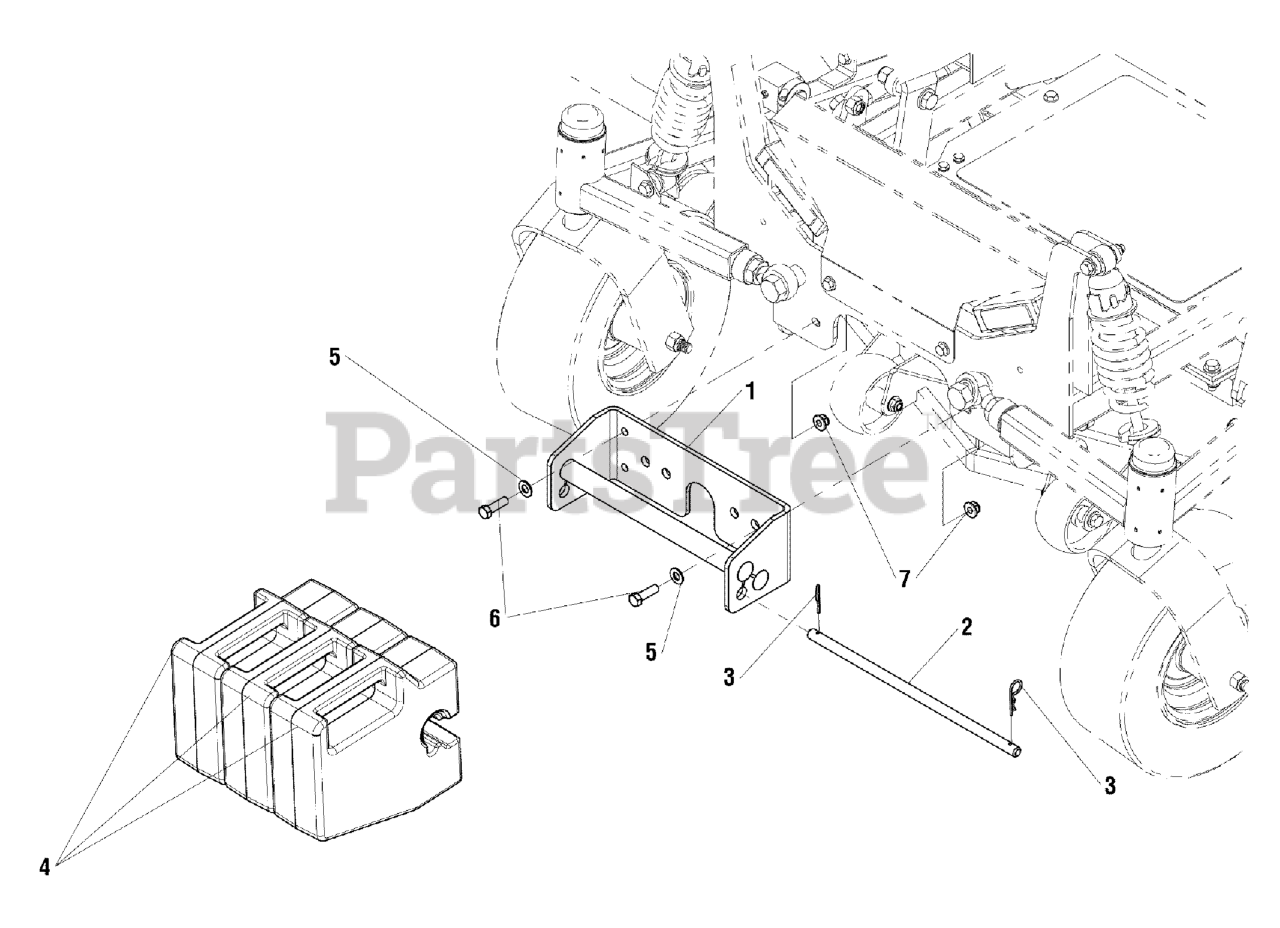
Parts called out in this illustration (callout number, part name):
1	HOLDER ASMY-WEIGHT CONS Z CAT - BLACK
2	ROD-.500DIA 13.75LG YELLOW CON
3	PIN, HAIR, .0915 X 1-7/8
4	WEIGHT-QUICK ATTACH 50LB SUITCASE PAINTED
5	WASHER, 3/8 SAE
6	BOLT, 3/8-16 X 1-1/4" GD5 CZ
7	NUT, 3/8-16 HEX NYLOCK FLANGE
